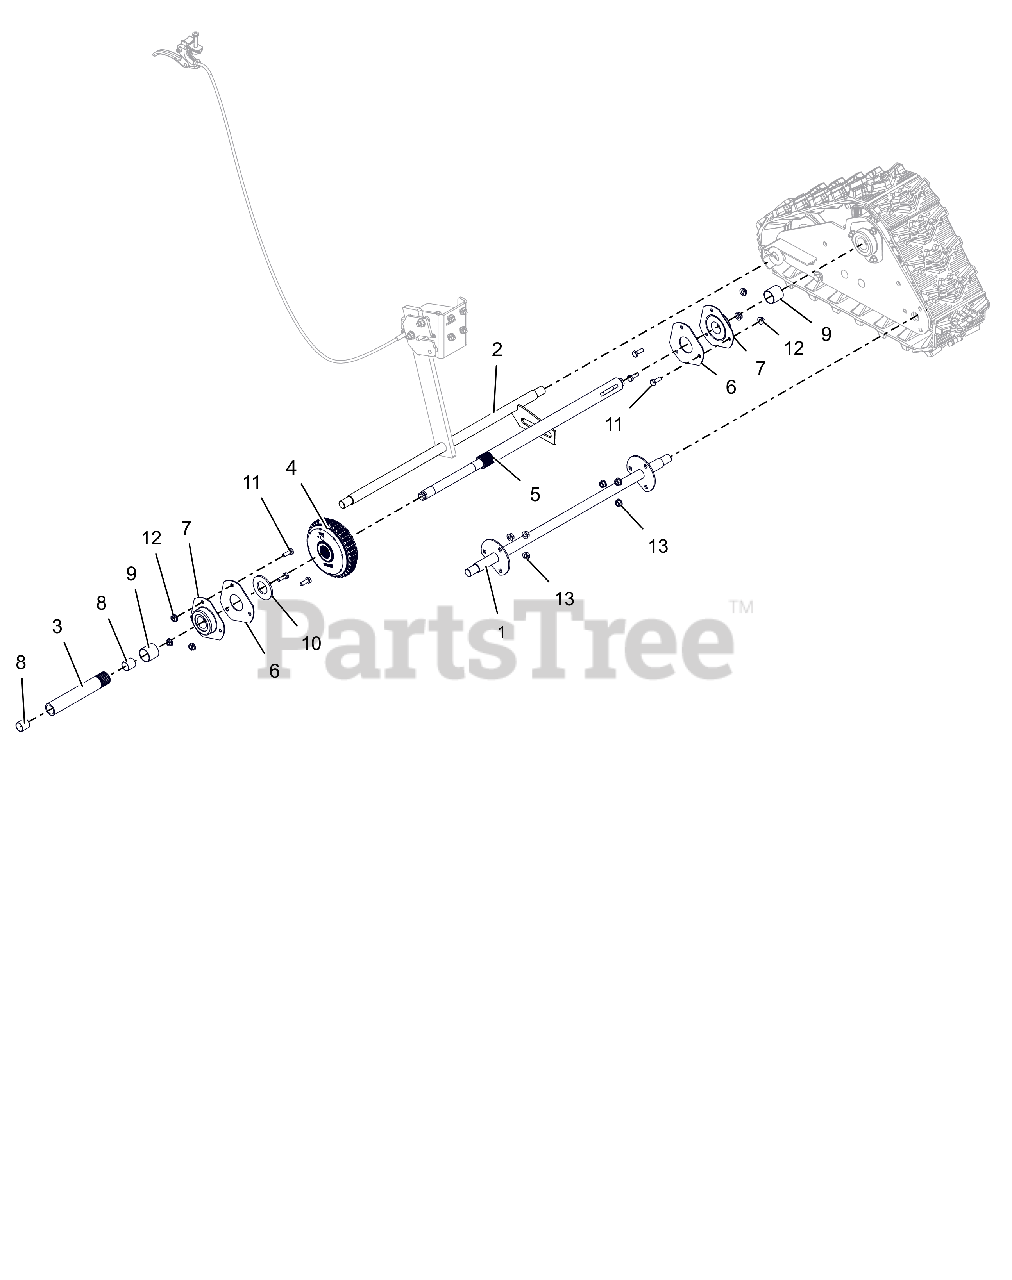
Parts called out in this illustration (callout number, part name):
1	AXLE, FRONT - PRO
2	AXLE, REAR - PRO TRACK
3	AXLE, SHORT-W/BUSHINGS
4	DIFFERENTIAL, AUTOMATIC
5	AXLE, LONG-TRACK DIFFERENTIAL
6	PLATE, BEARING SPACER
7	BRG-FLG 1.003/1.000 3 BOLT
8	BSHG-SLV .706X.764X.75 BRZ
9	BSHG-SLV, 1.012X1.125X1.00
10	WSHR-FL-STL- 1.062X2.0X.134 YZ
11	@BLT-HEX .25-20X.75 GR5 YWZC
12	@NUT-LK-CTR-FLG .25-20 YWZC
13	@NUT-LK-TOP-FLG .25-20 YWZC
